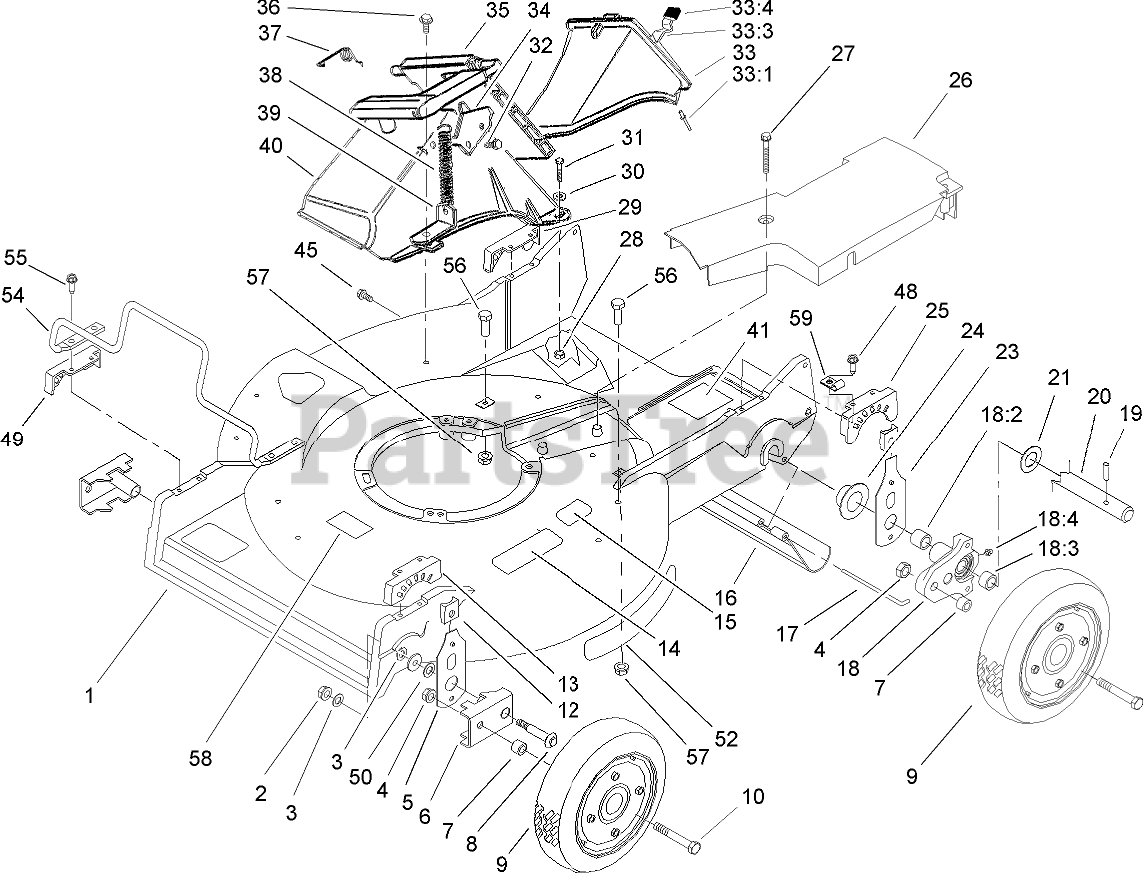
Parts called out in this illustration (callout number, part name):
1	HOUSING ASM
2	NUT-LOCK
3	WASHER
4	NUT-LOCK, CONE
5	FRONT SPRING ARM ASM
6	ARM-PIVOT, FRONT
7	SPACER-WHEEL
8	BOLT-WHEEL
9	Wheel and Tire ASM
10	SCREW-HH
12	KNOB-ARM
13	QUADRANT-FRONT, LH
14	Decal-Warning
15	DECAL-STD, SAFETY
16	SHIELD-TRAILING
17	ROD-SHIELD
18	PIVOT ARM ASM
18:2	BUSHING
18:3	BUSHING
18:4	FITTING-GREASE
19	PIN-SPIROL
20	SHAFT-AXLE, REAR
21	WASHER-PLAIN
23	REAR SPRING ARM ASM
24	CAP-END
25	QUADRANT-REAR, LH
26	COVER-BELT
27	SCREW-HHFTF
28	NUT-LOCK, NI
29	QUADRANT-REAR, RH
30	WASHER-FLAT
31	SCREW-HH
32	SCREW-PLASTITE
33	DISCHARGE PLUG ASM
33:1	RIVET-HEAD, FLAT
33:3	LATCH-PLUG, DISCHARGE
33:4	GRIP-LATCH
34	LATCH-PLATE
35	DISCHARGE DOOR ASM
36	SCREW-HWH
37	RETAINER-DOOR
38	SPRING-DOOR
39	BRACKET-SPRING
40	TUNNEL-DISCHARGE
41	LABEL-GREASE, HP
45	SCREW AND WASHER ASM
48	SCREW-HWHTF
49	QUADRANT-FRONT, RH
50	WASHER-THRUST
54	GUARD-ENGINE
55	SCREW-HWHTF
56	SCREW-HH
57	NUT-LOCK, NI
58	DECAL-BLADE
59	CLIP-CLOSED, INSULATED
